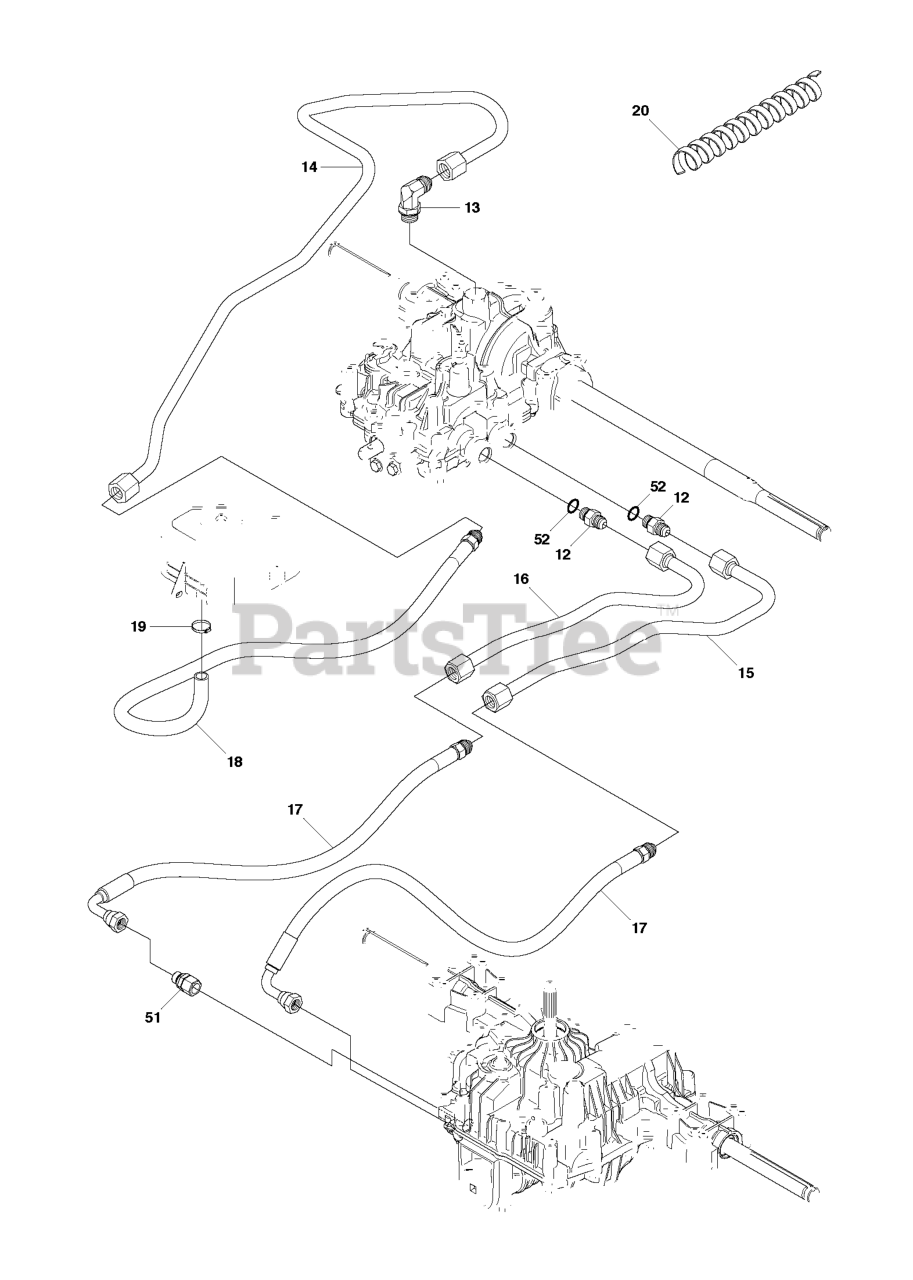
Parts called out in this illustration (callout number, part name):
12	PIPE FITTING
15	HYDRAULIC PIPE
16	HYDRAULIC PIPE
17	HYDRAULIC HOSE
20	HOSE GUARD D=43 L=400
